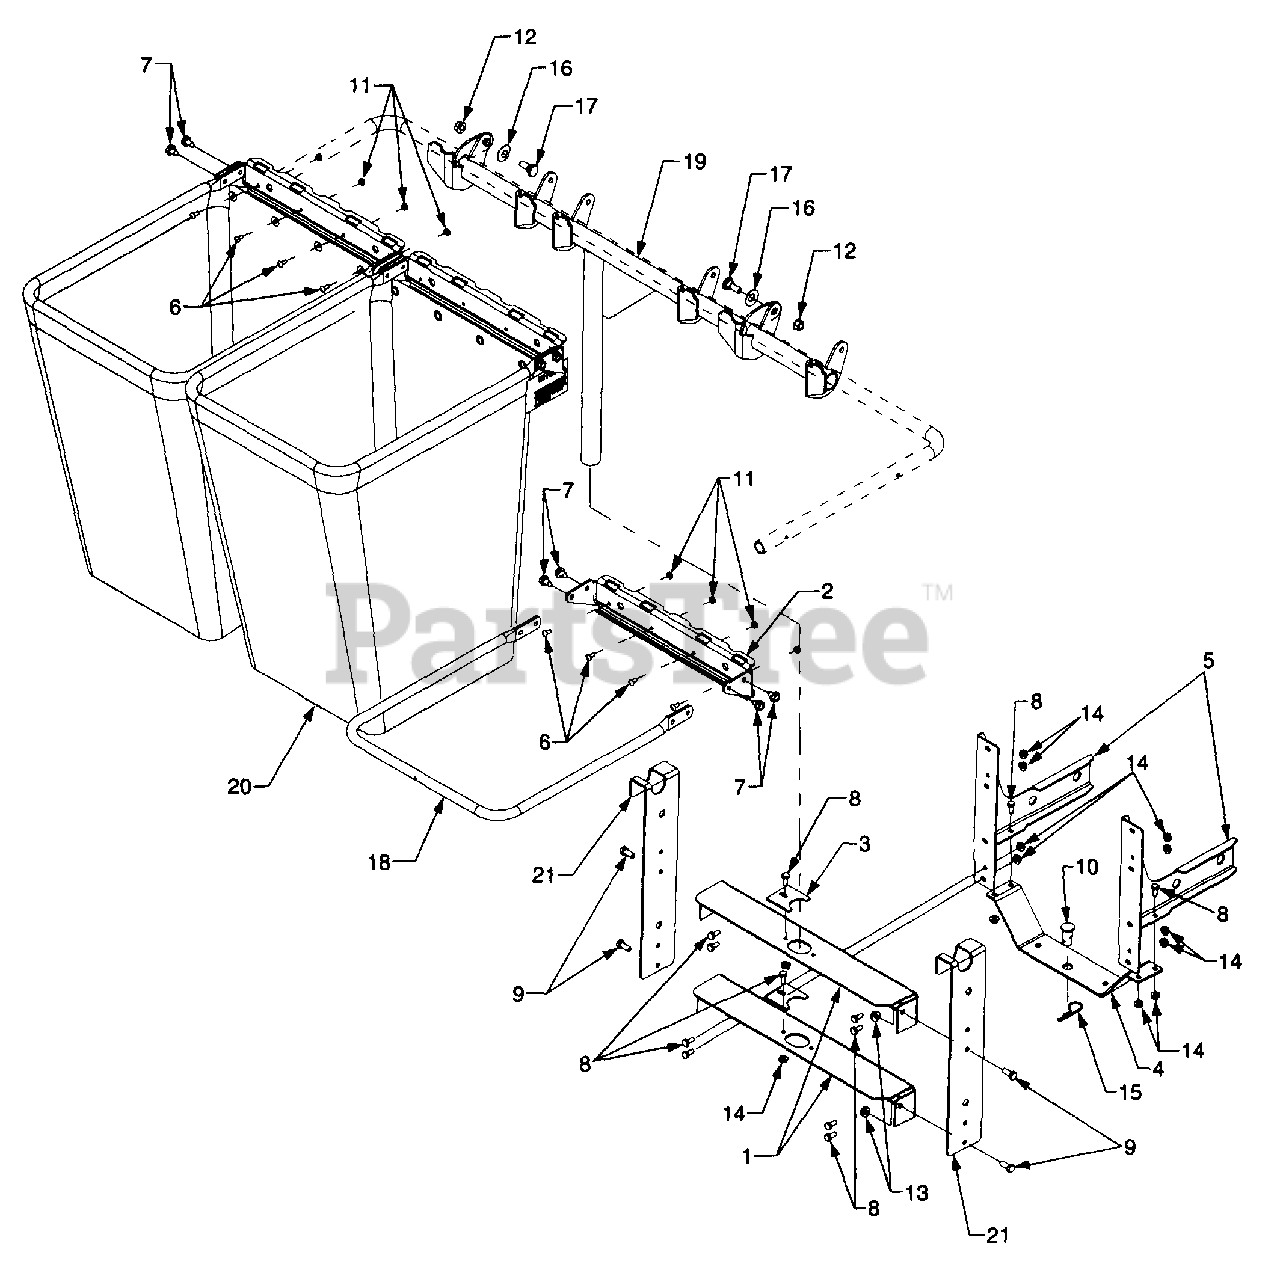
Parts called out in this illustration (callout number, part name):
1	Bracket, Catcher Support
2	Bracket, Bag Frame Hanger
3	Bracket, Support Tube Adapter
5	Bracket, Frame Support
6	Screw, Truss Hd. Mach. 10-24 x .5
7	Screw, Hex Wash. Hd. Tapp 5/16-18 x .625
8	Screw, Hex Cap 1/4-20 x .62 GR5
9	Screw, Hex Cap 5/16-18 x .75 GR5
10	Pin, Clevis, .62 Diam.
11	Nut, Hex Sems, 10-24
12	Nut, Hex Flange Lock, 3/8-16
13	Nut, Hex Flange Lock, 5/16-18
14	Nut, Hex Flange Lock, 1/4-20
15	Pin, Internal Cotter
16	Washer, Belleville, .51 x 1.14 x .04
17	Screw, Shoulder .50 x .27: 3/8-16
18	Tube, Grass Bag Frame
19	Support Tube Assembly
20	Bag, Grass Catcher
21	Bracket, Tube Assembly Support
